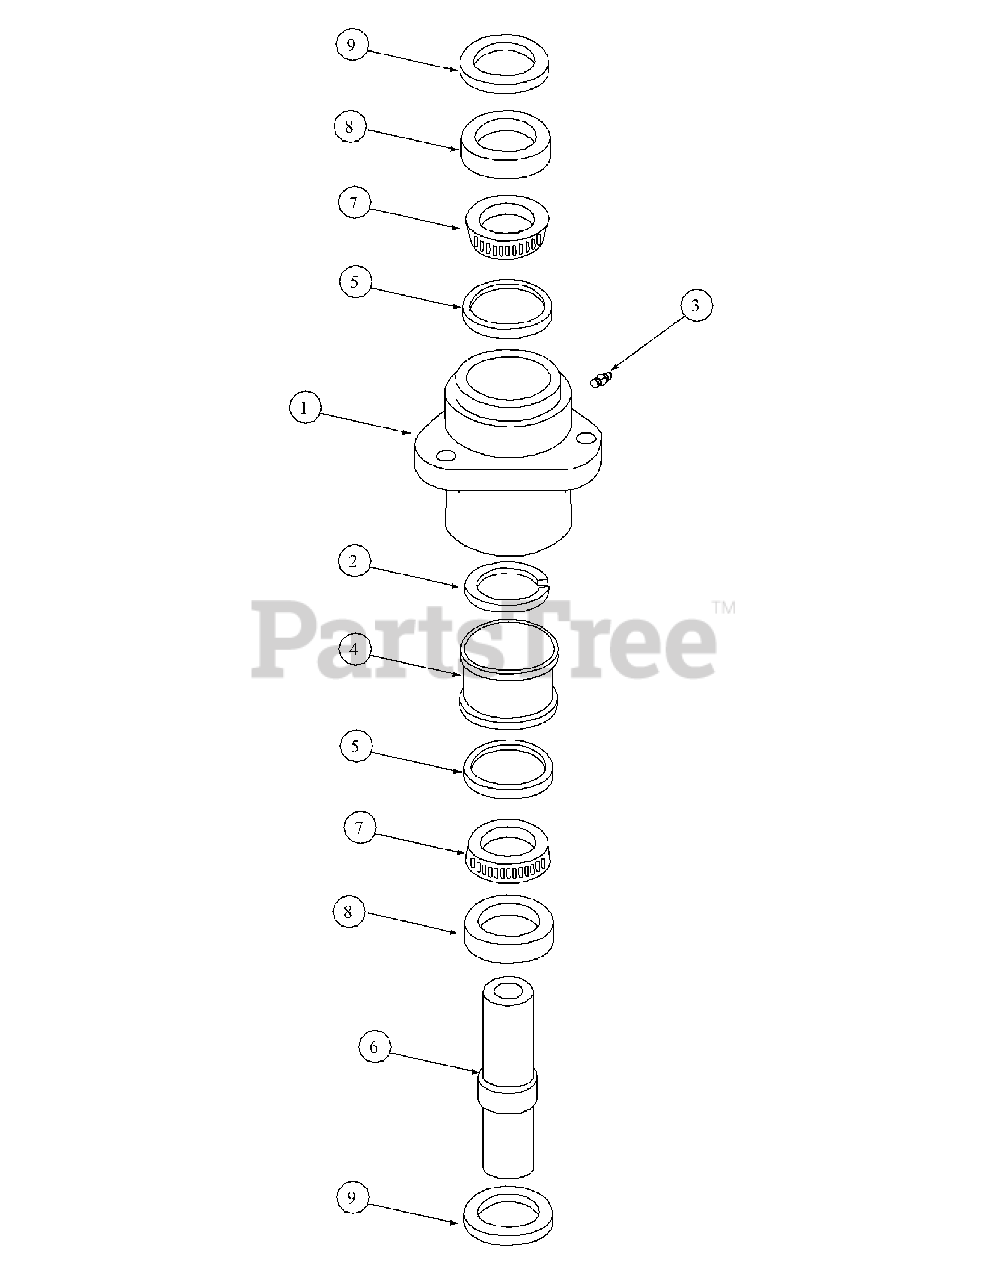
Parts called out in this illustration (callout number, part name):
1	Spindle Housing
2	Spacer Bearing
3	Grease Fitting
4	Spacer
5	Cup Bearing
6	Shaft Blade Spindle
7	Cone Bearing
8	Ring Seal
9	Oil Seal
